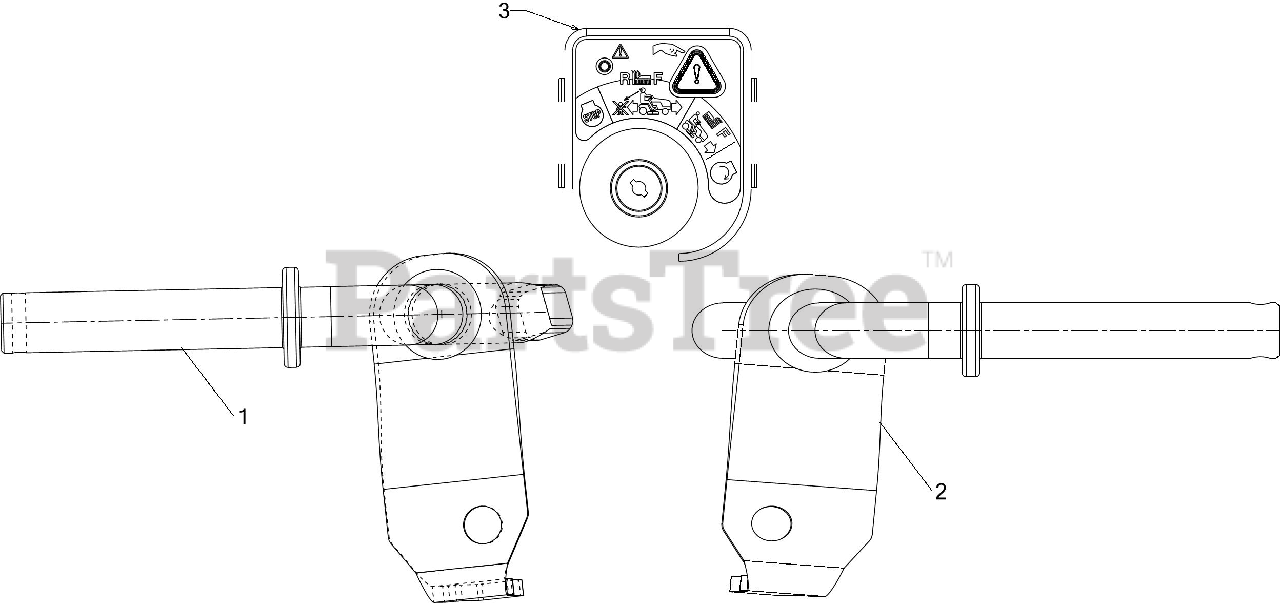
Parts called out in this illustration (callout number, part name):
1	FRONT AXLE ASSEMBLY (RH)
2	FRONT AXLE ASSEMBLY (LH)
3	IGNITION MODULE SWITCH RMC (MAN PTO BLK)
